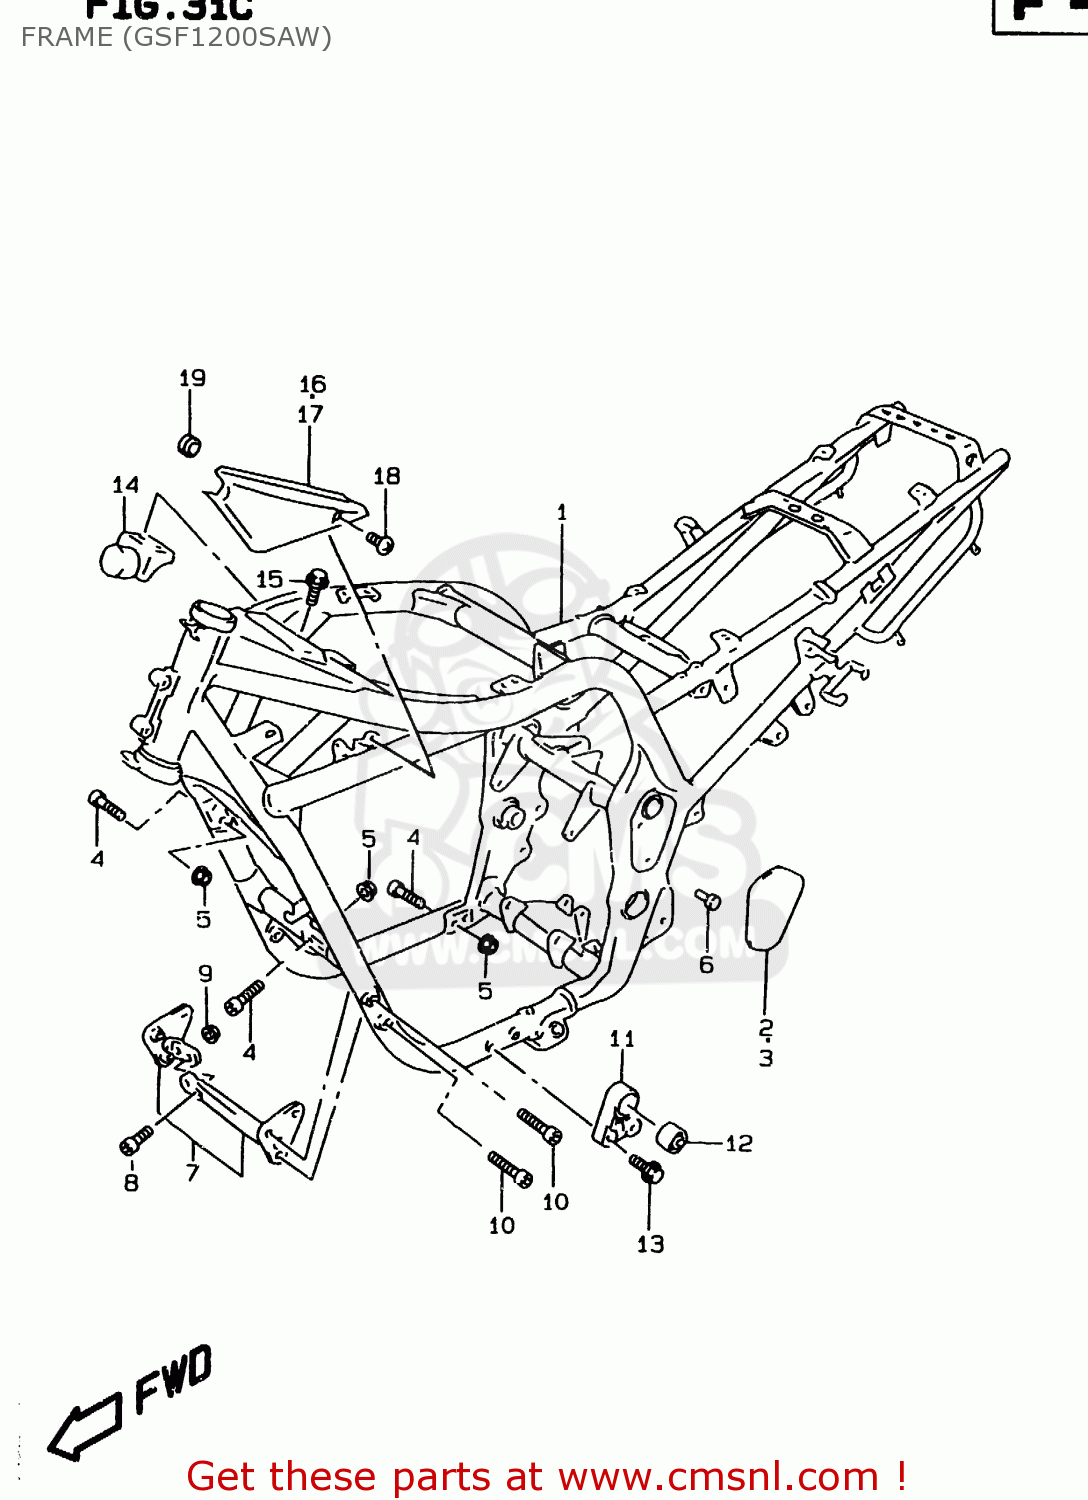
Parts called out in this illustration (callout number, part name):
1	FRAME COMP
2	COVER,FRAME BODY,R
3	COVER,FRAME BODY,L
4	BOLT(10X33)
5	NUT
6	CLIP
7	PLATE ASSEMBLY,ENGINE MOUNT
8	BOLT
9	NUT
10	BOLT
11	BRACKET,ENGINE MOUNTING NO.2
12	BUSH,ENG MOUNTING NO.2
13	BOLT
14	DAMPER COMP,FRAME
15	BOLT
16	COVER,FRAME HEAD,R
17	COVER,FRAME HEAD,L
18	SCREW(5X12)
19	CUSHION
